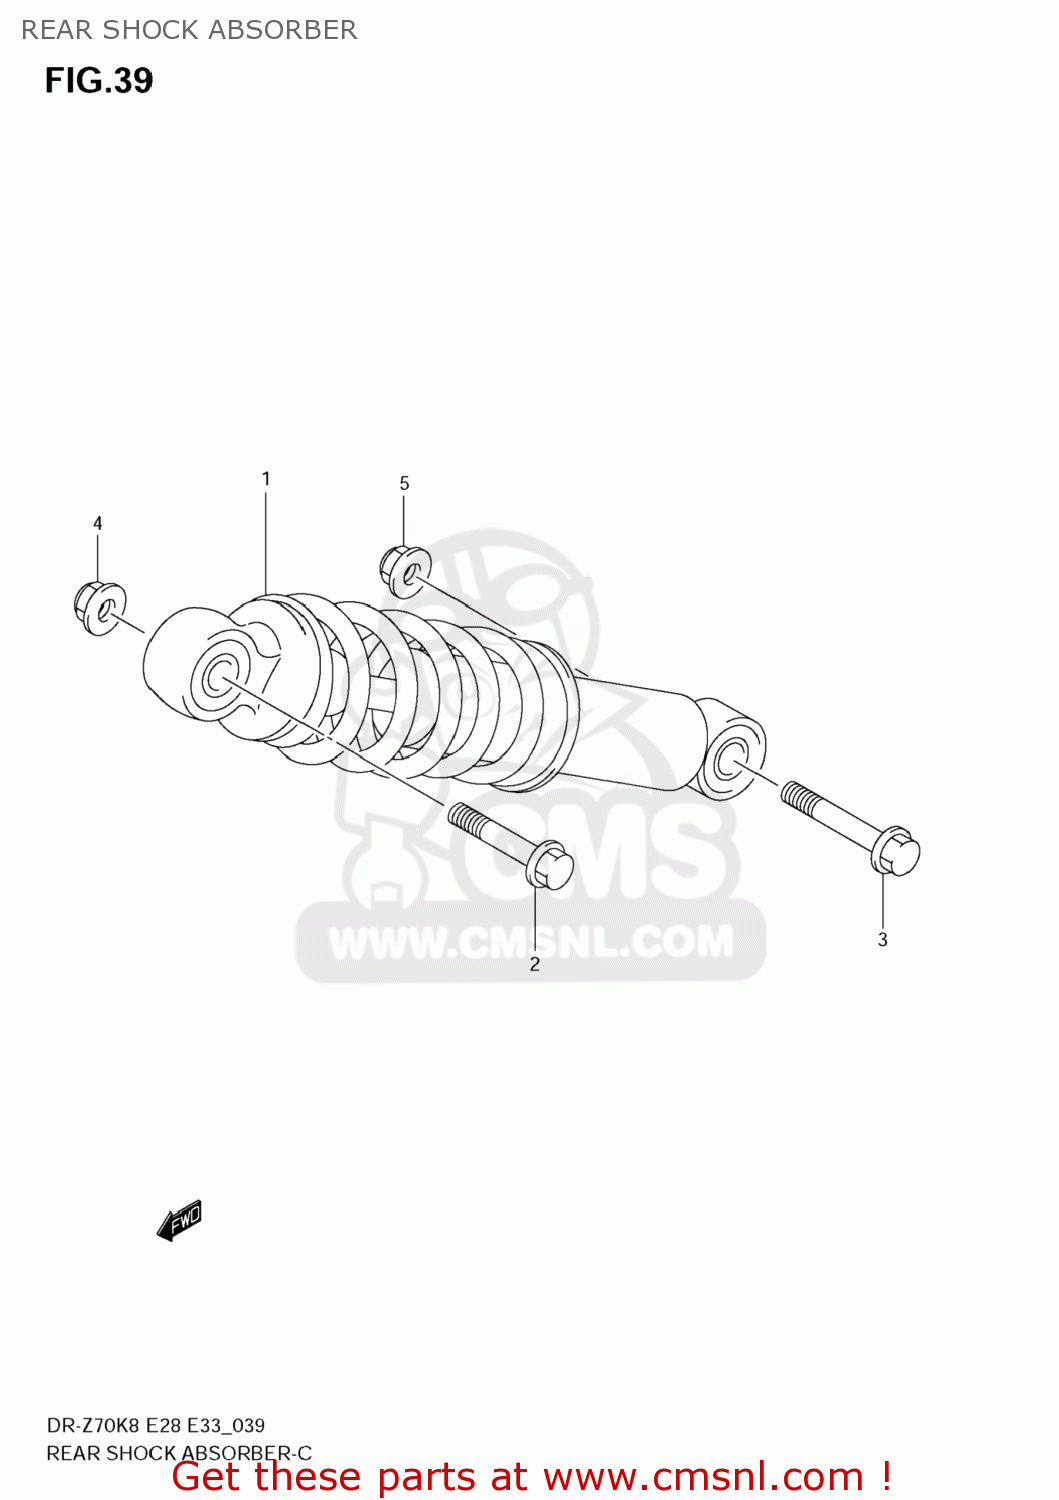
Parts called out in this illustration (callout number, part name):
1	ABSORBER ASSY,RR SHOCK
2	BOLT(10X37)
3	BOLT(10X43)
4	NUT
5	NUT
